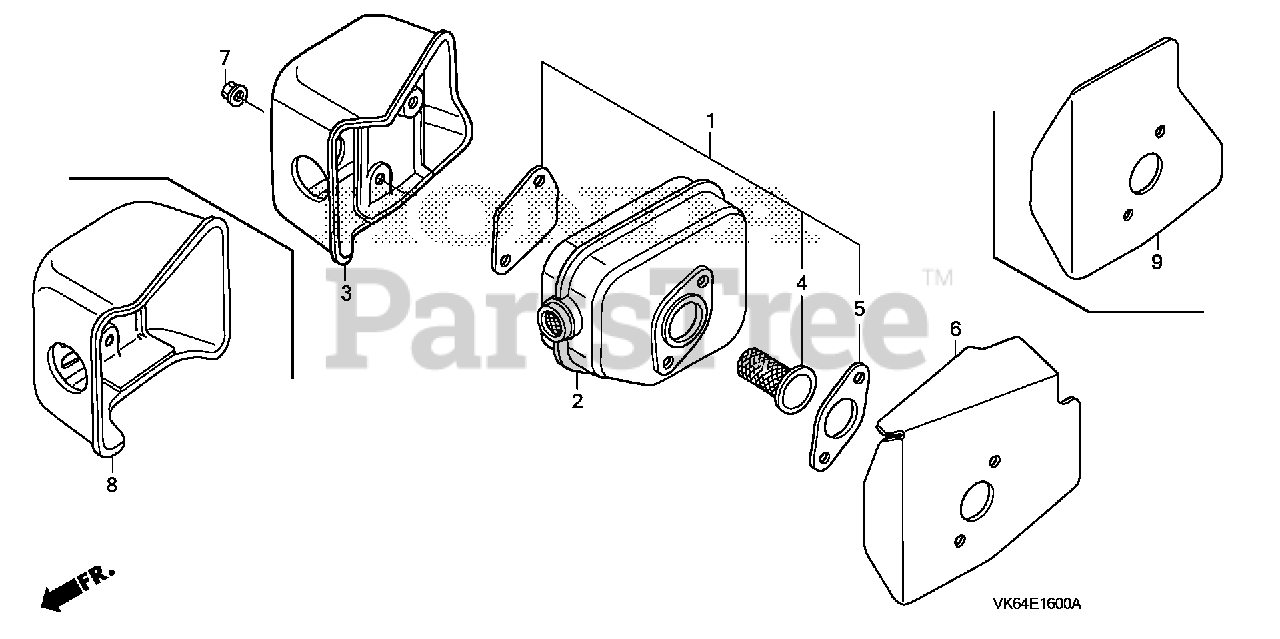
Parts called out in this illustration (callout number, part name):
1	ARRESTER KIT, SPARK
2	MUFFLER
4	ARRESTER KIT, SPARK
5	GASKET, MUFFLER
7	NUT, SELF-LOCK (6MM)
8	PROTECTOR, MUFFLER
9	GASKET, MUFFLER
